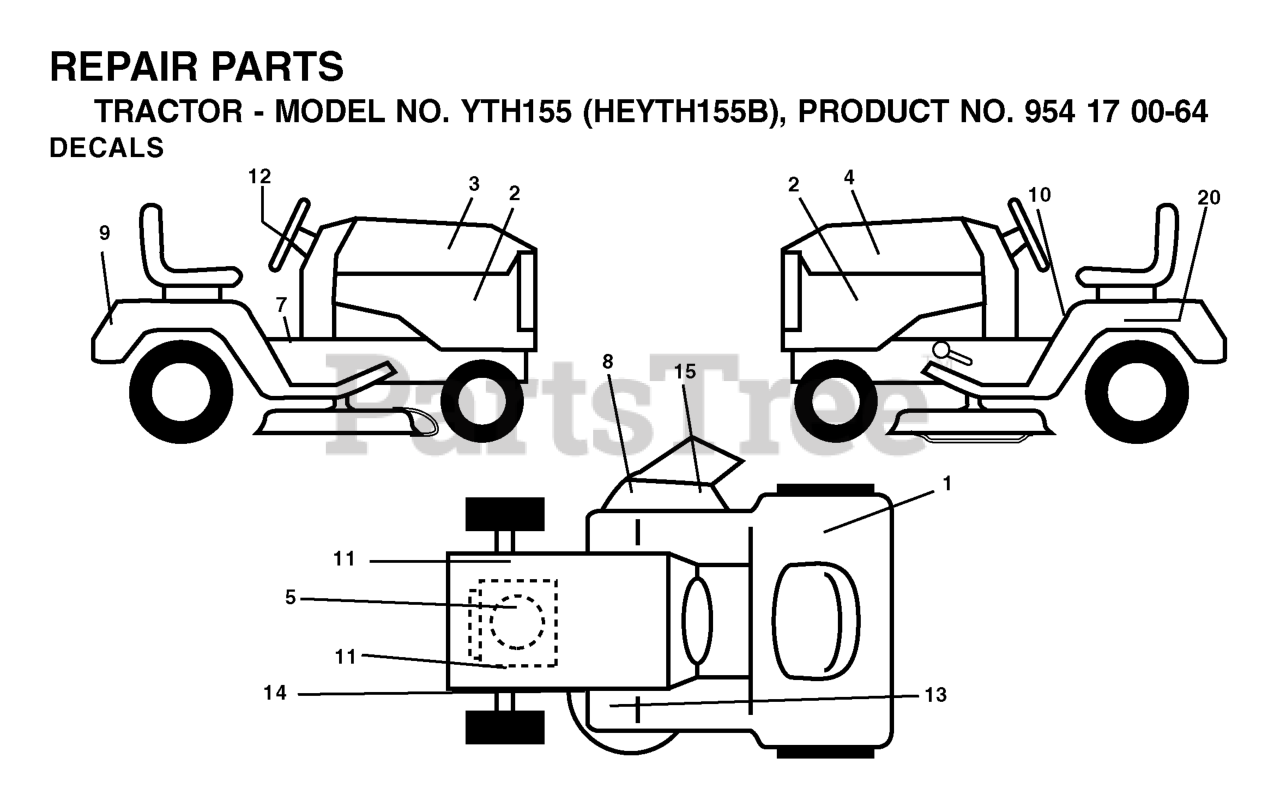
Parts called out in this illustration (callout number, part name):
1	Decal, Fender 100 DB/CE
2	DECAL PNL SIDE
7	DECAL PARK BRAKE
8	DECAL.INTERNATIONL.CUTFINGER
9	DECAL FENDER HUSQ
10	DECAL READ OWNER'S MAN SYMS
12	DECAL.WHEEL.STEERING.HUSQ.PERM
13	DECAL
14	DECAL V BELT SCHEMATIC
15	DECAL DECK "B" 42"
20	DECAL BTRY SYMBOLS
